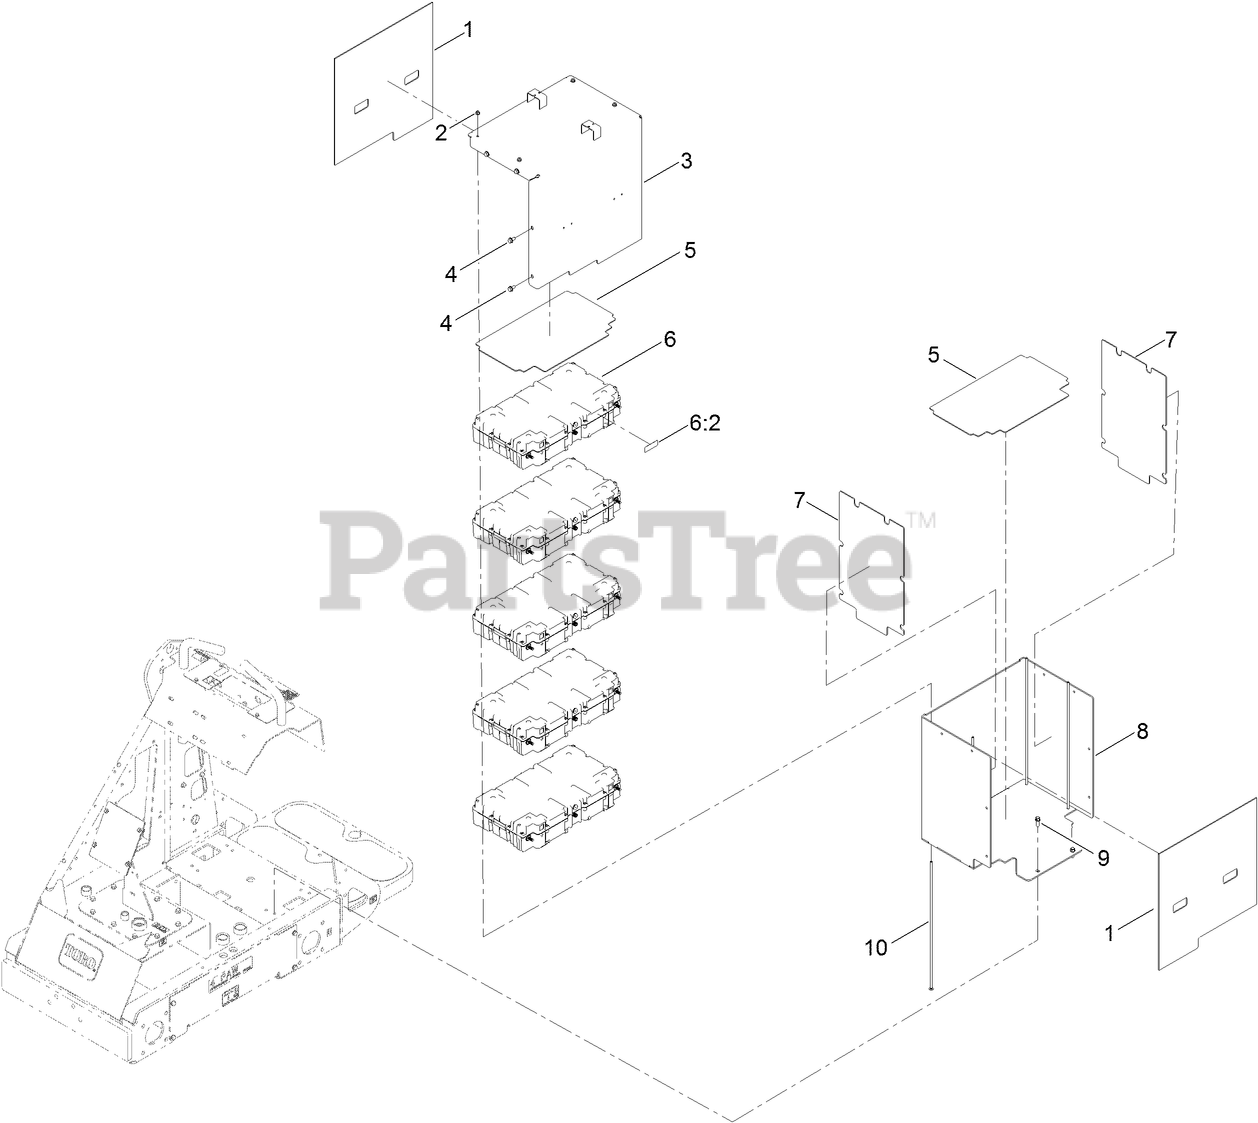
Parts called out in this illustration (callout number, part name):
1	FOAM-BATTERY, MAIN
2	NUT-FLANGE, NI
3	COVER BATTERY
4	SCREW-HWHTF
5	FOAM-BATTERY, MAIN
6	BATTERY SERVICE ASM
6:2	DECAL-SAFETY
7	FOAM-BATTERY, MAIN
8	ENCLOSURE-BATTERY
9	SCREW-TAPTITE
10	SCREW-CARR
